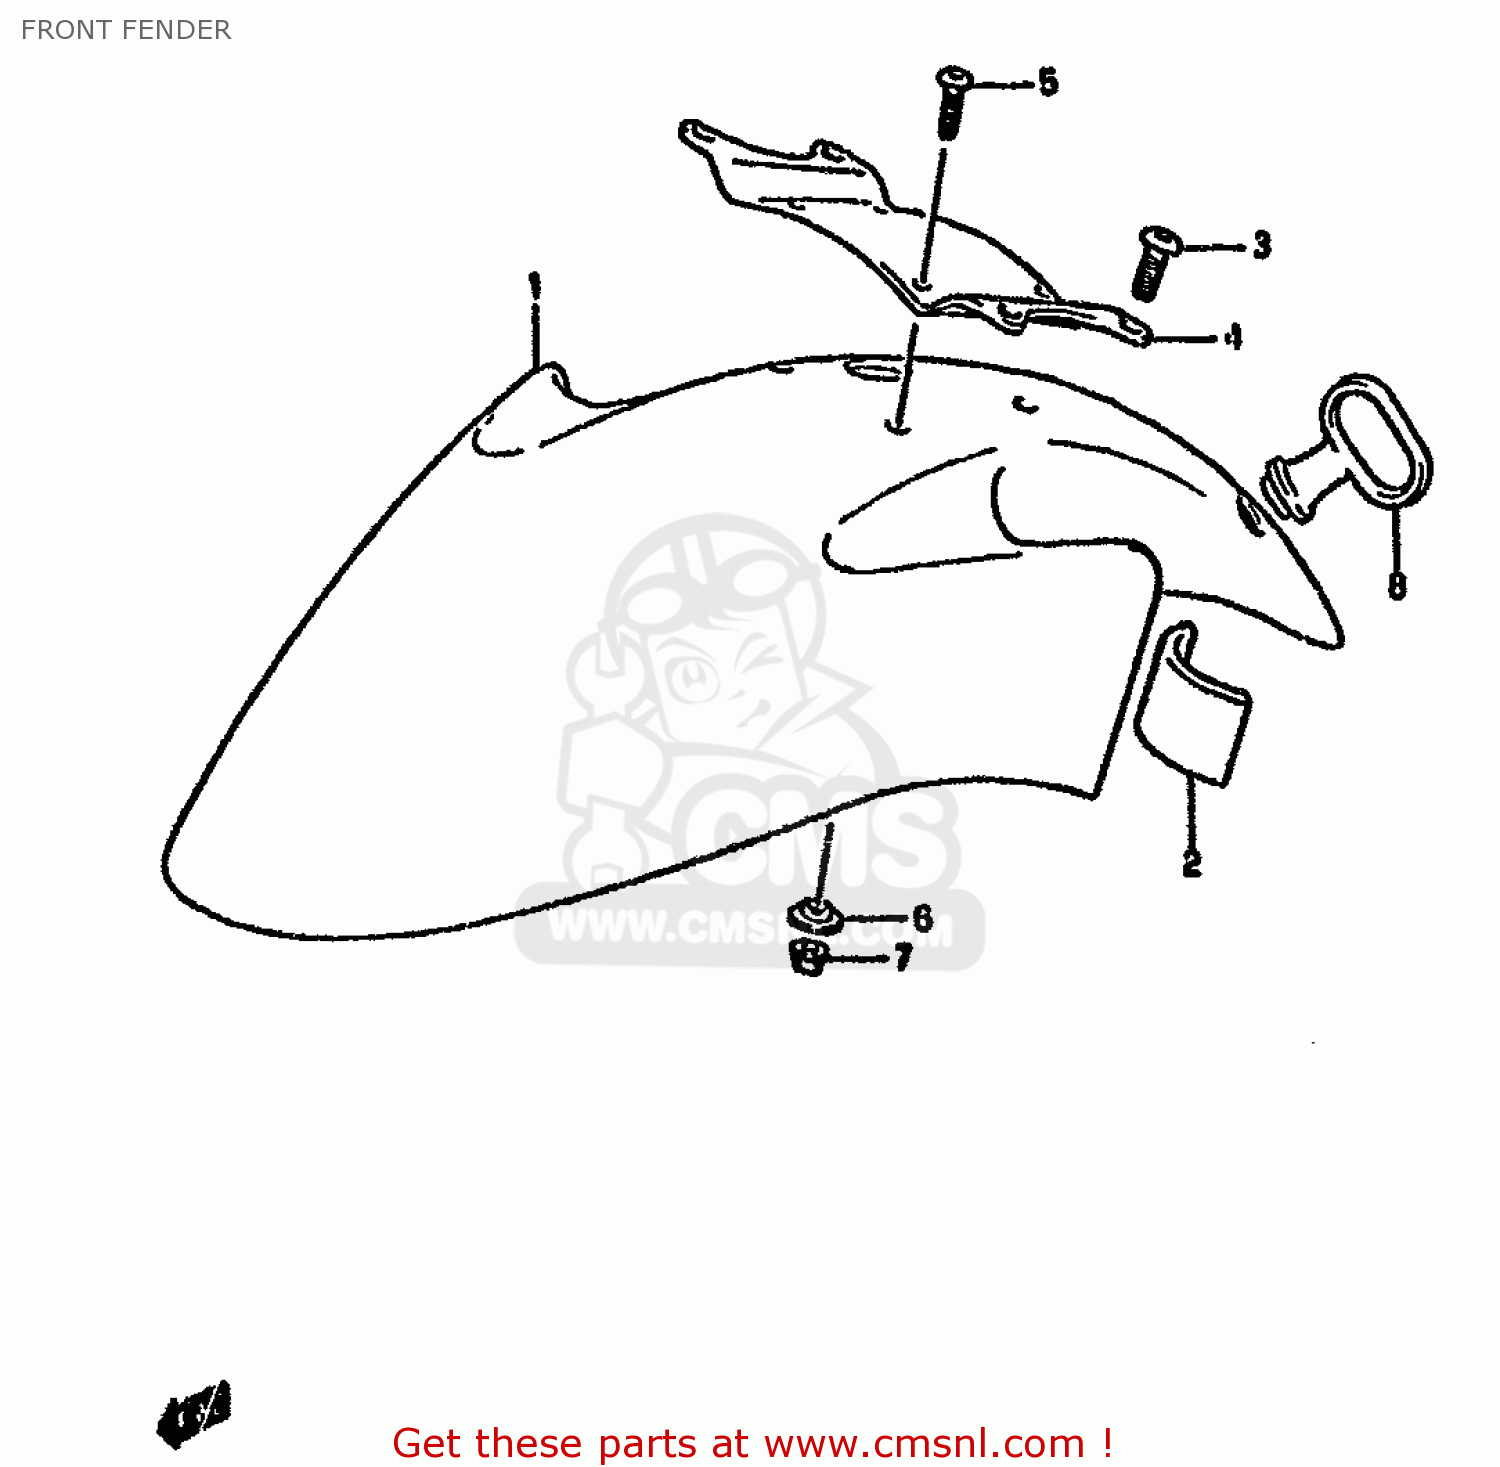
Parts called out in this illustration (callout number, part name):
1	FENDER,FR
2	CUSHION,FR FENDER
3	SCREW(6X12)
4	BRACE,FR FENDER
5	SCREW(5X16)
6	WASHER
7	NUT
8	GUIDE,CABLE
